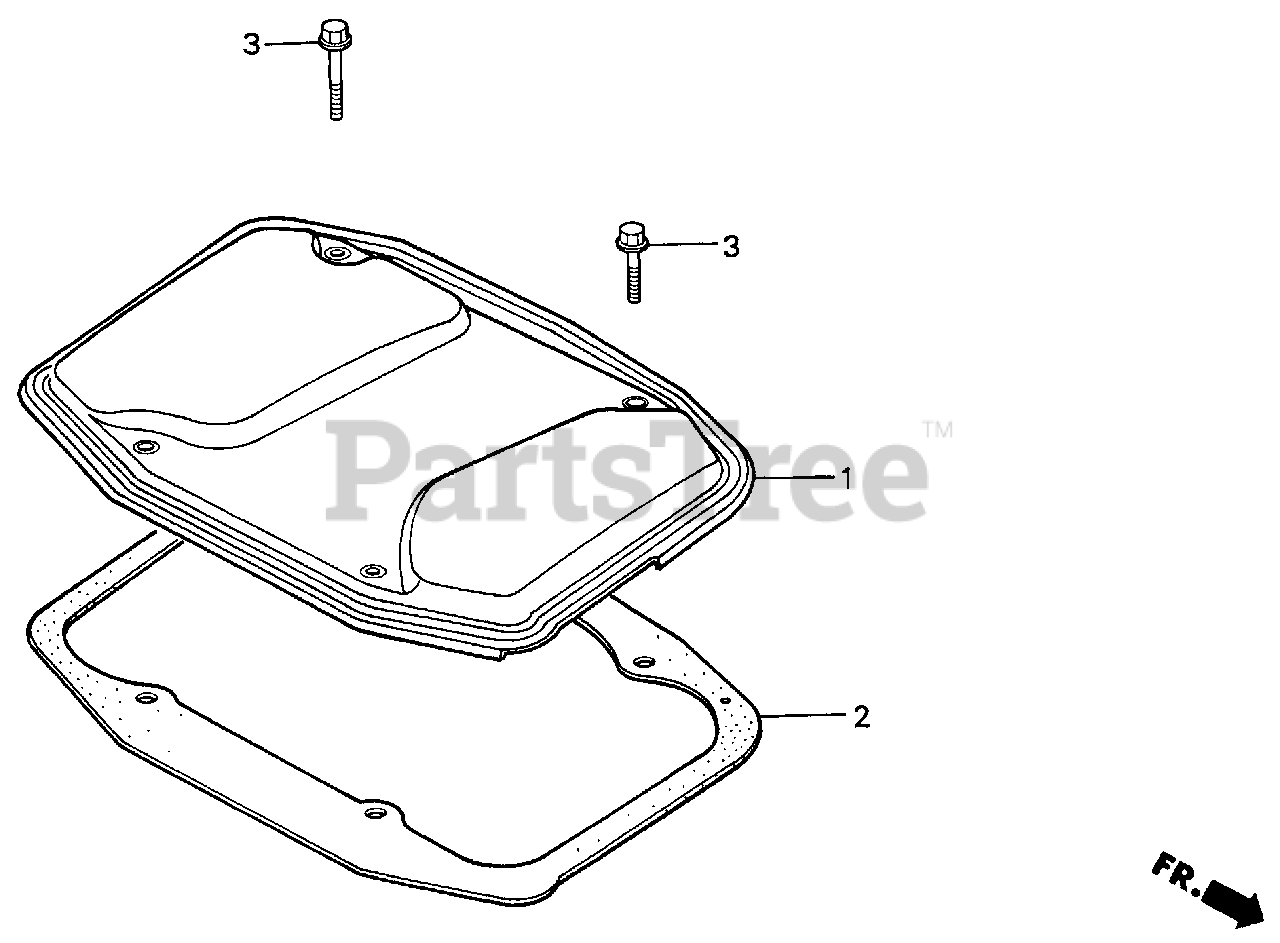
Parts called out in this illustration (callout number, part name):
1	COVER, CYLINDER HEAD
2	GASKET, CYLINDER HEAD COVER
3	BOLT, FLANGE (6X20)
